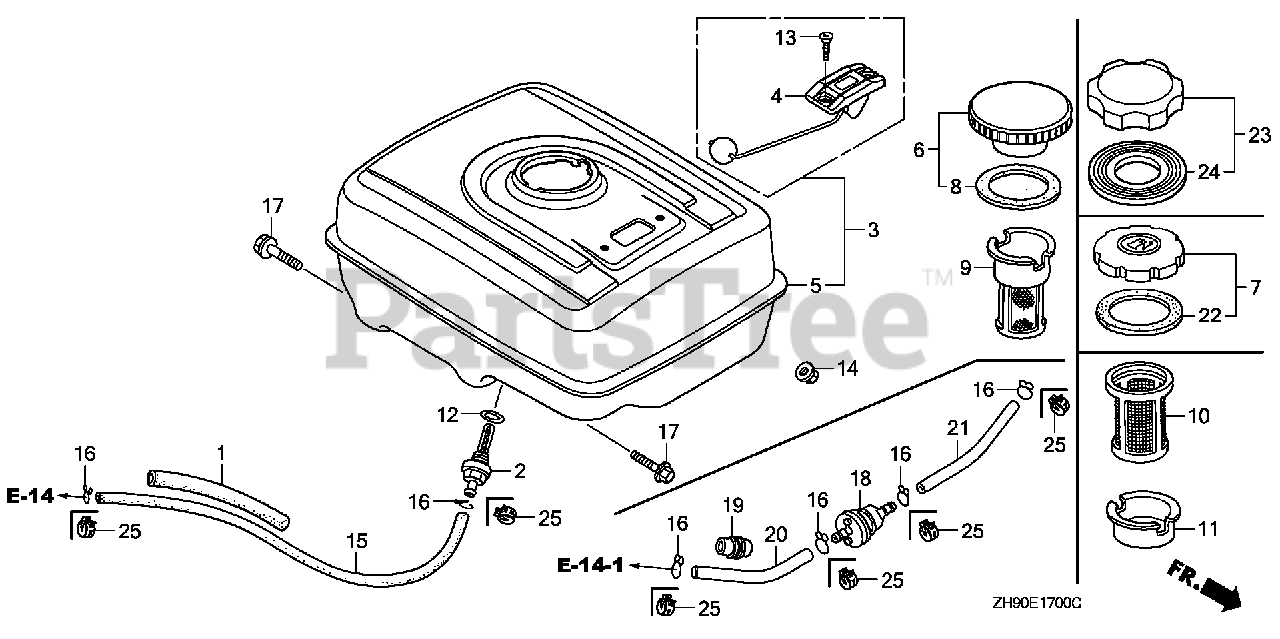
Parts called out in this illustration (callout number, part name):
1	RUBBER, SUPPORTER (107MM)
2	JOINT, FUEL TANK
5	TANK, FUEL *NH1* (BLACK)
5	TANK, FUEL *NH31* (MCKINLEY WHITE)
7	CAP, FUEL FILLER (BLACK)
9	FILTER, FUEL
12	O-RING (14MM) (ARAI)
12	O-RING (14MM) (NOK)
14	NUT, FLANGE (8MM)
15	BULK HOSE, FUEL (4.5X3000) (4.5X222)
16	CLIP, TUBE (B8)
17	BOLT, FLANGE (8X25)
22	GASKET, FUEL FILLER CAP (39X58X3)
23	CAP, FUEL FILLER (CHROME PLATED)
24	GASKET, FUEL FILLER CAP (39X62X3) (TOUYOUSYA)
